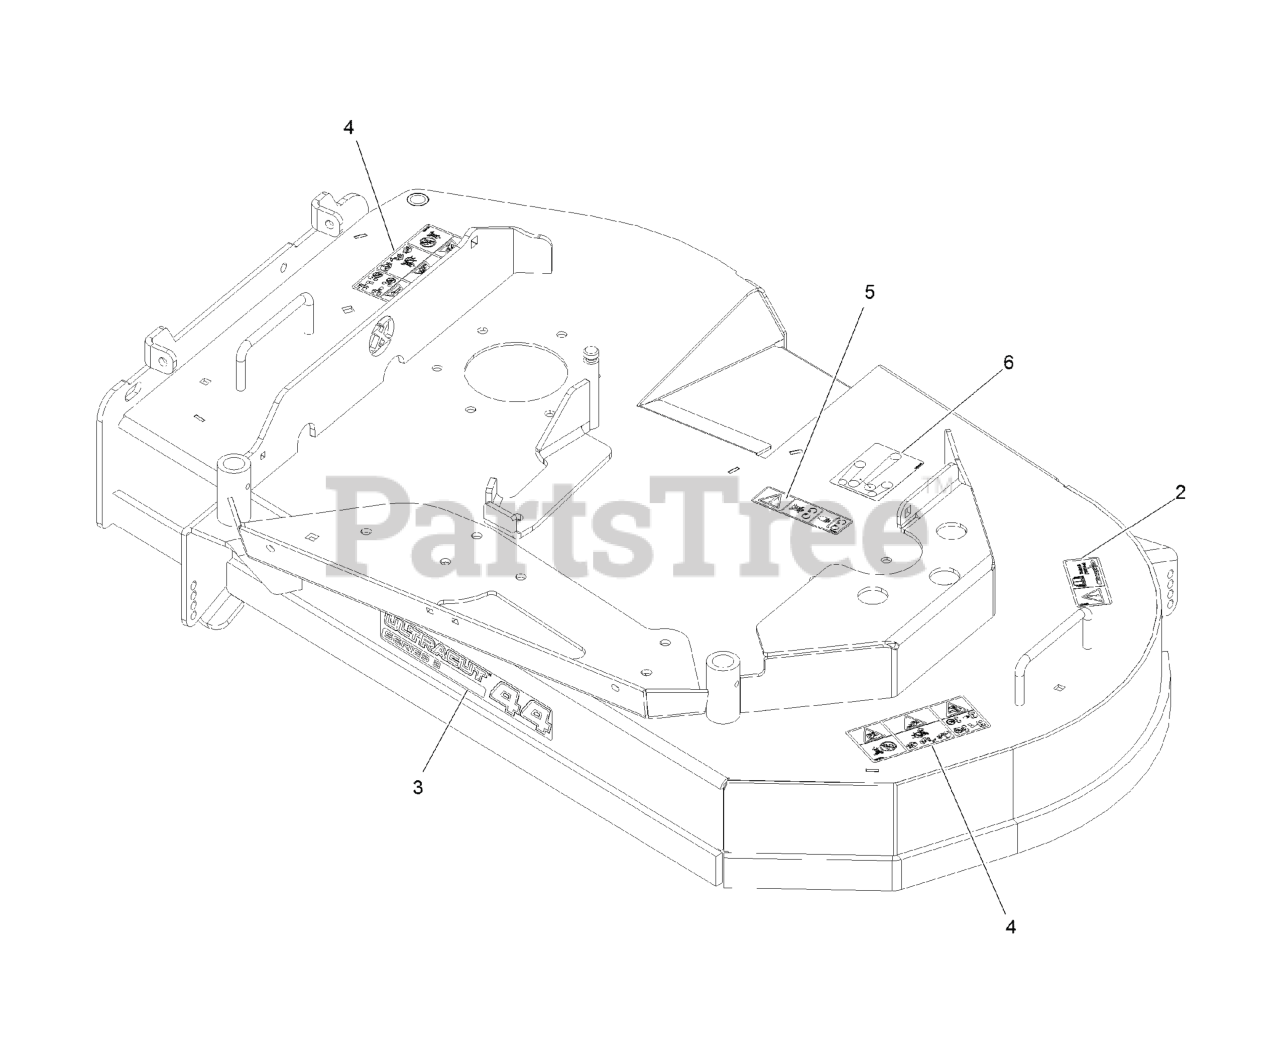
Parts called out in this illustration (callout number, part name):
2	DECAL-TORQUE, BOLT
3	DECAL-ULTRACUT 44 SERIES 3
4	DECAL-WARNING THROWN OBJ
5	DECAL-COVER, MISSING
6	DECAL-BELT ROUTING
